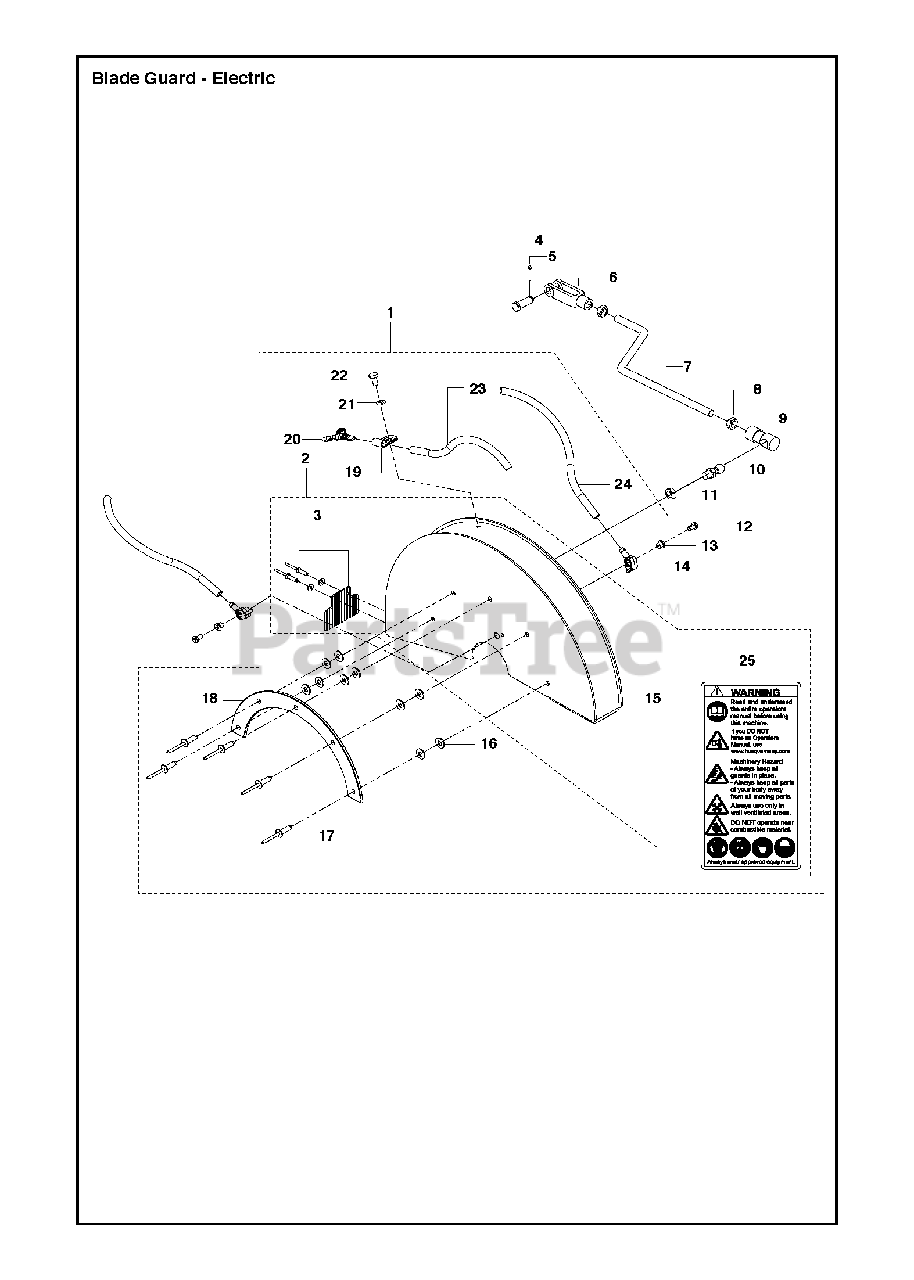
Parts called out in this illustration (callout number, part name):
5	PIN, COTTER .0937 X .625
9	QUICK DISCONNECT-BODY
10	QUICK DISCONNECT-BALL MACH
12	SCREW ITXSCM
16	WASHER 1/4 SAE
22	HCS ¼-20 X ½ GR 5 ZD
23	HOSE
24	HOSE
